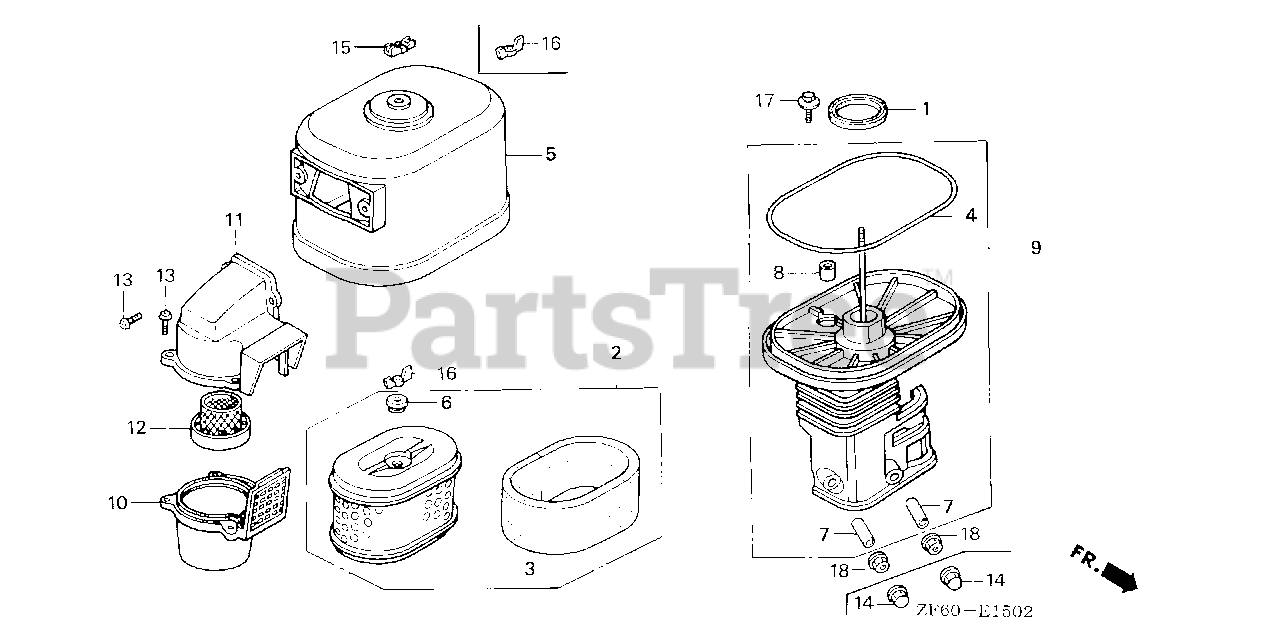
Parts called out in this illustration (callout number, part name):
1	GASKET, ELBOW
2	ELEMENT, AIR CLEANER
3	FILTER (OUTER)
4	SEAL, AIR CLEANER COVER
5	COVER, AIR CLEANER (CYCLONE)
6	GROMMET, AIR CLEANER
7	COLLAR, AIR CLEANER
8	COLLAR B, AIR CLEANER
9	ELBOW, AIR CLEANER
10	CASE, PRE AIR CLEANER
11	CAP, PRE AIR CLEANER
12	GUIDE, PRE AIR CLEANER
13	SCREW, PAN (5X16.5)
14	NUT, CAP (6MM)
15	NUT, AIR CLEANER COVER (DACRO COATING)
15	WINGNUT (6MM) (BLACK)
16	NUT, TOOL BOX SETTING
17	BOLT-WASHER (6X22)
18	NUT, FLANGE (6MM)
